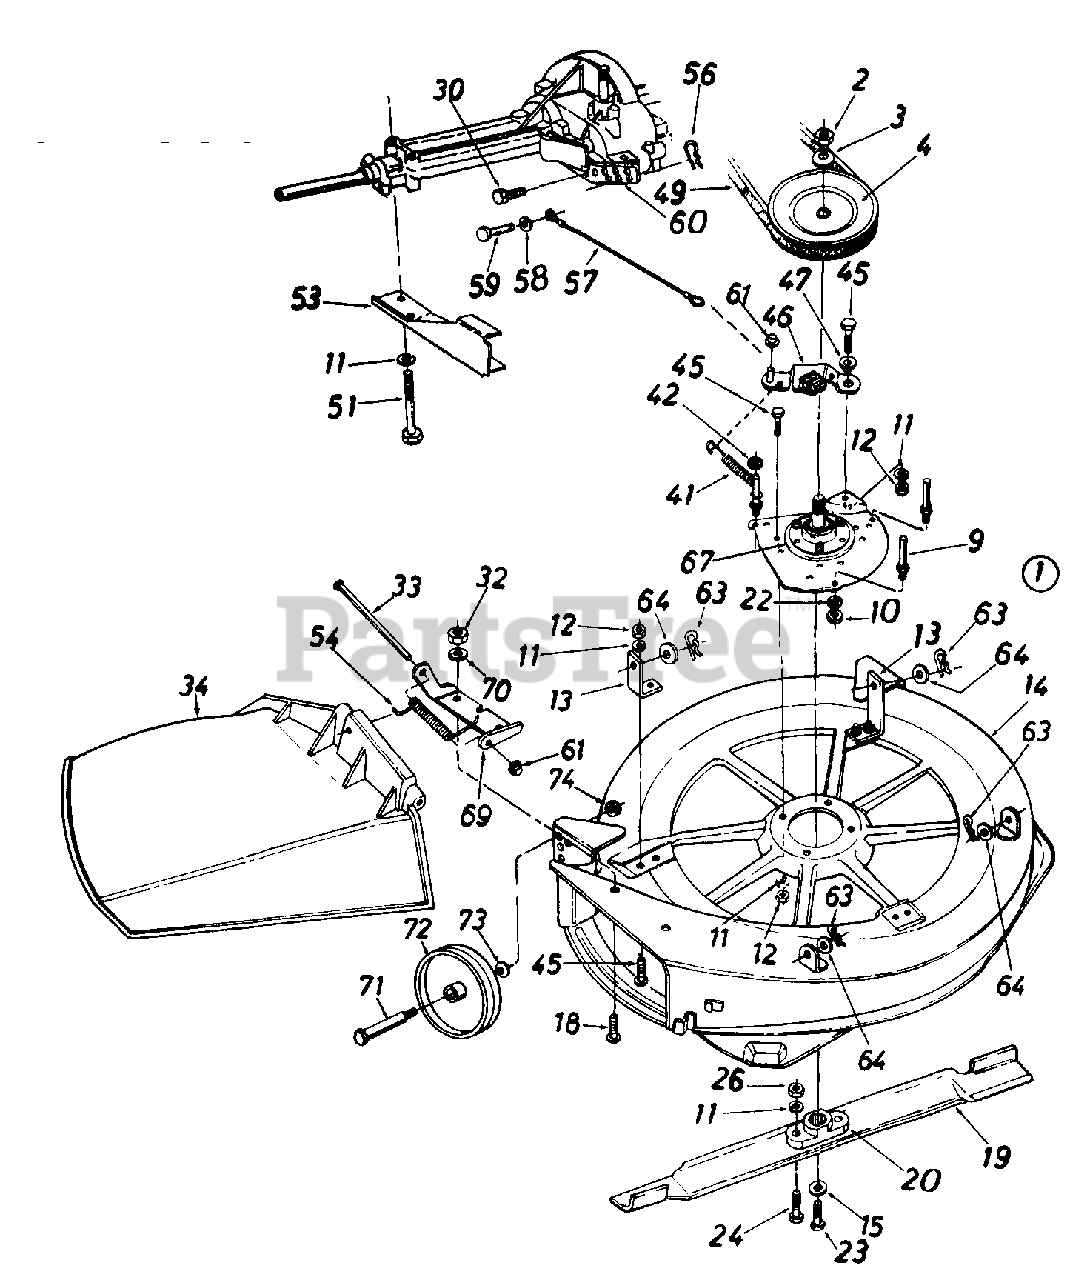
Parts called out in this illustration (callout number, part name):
3	Bell-Wash..630" I.D. x 1.25"
4	5/8 V-Pulley .75" I.D. x 7"
9	Stud 3/8-16 x 2.75" Lg.
10	Hex Jam Nut 3/8-16 Thd.
11	L-Wash. 5/16" I.D.
12	Hex Nut 5/16-18 Thd.
18	Hex Bolt 1/4-20 x .62" Lg.
19	30" High Lift Blade
20	Blade Adapter
22	L-Wash. 3/8" I.D.
23	Hex Bolt 3/8-24 x 1.0
24	Hex Bolt 5/16-24 x 1.0" Lg.
26	Hex Nut 5/16-24 Thd.
30	Hex Bolt 1/4-20 x .50" Lg
32	Hex Nut 1/4-20 Thd.
33	Hinge Pin
34	Chute Ass'y. Comp.
41	Extension Spring
42	Push Speed Nut
45	Hex Bolt 5/16-18 x .75"
46	Blade Brake Brkt. Ass'y.
47	Shoulder Spacer .500" Dia.
49	"V"-Belt
51	Hex Bolt 5/16-18 x 2 75"
56	Int. Cot. Pin 5/16" Dia.
57	Brake Cable 9.75" Lg.
58	Fl-Wash. 281" I.D. x .50"
59	Clevis Pin 1/4" Dia.
60	Lower Inside Belt Guard
61	Cap Speed Nut 1/4" Rod
63	int. Cotter Pin 1/2" Dia.
64	FI-Wash..531" I.D. x.930"
67	Blade Spindle Ass'y. Comp.
69	Hinge Mtg Brkt.
70	Bell-Wash 1/4" I.D.
71	Shld. Scr .498" x 1.53" Lg.
72	Deck Wheel
73	Bell-Wash 38" I.D. x 88"
74	Hex L-Nut 3/8-16 Thd.
